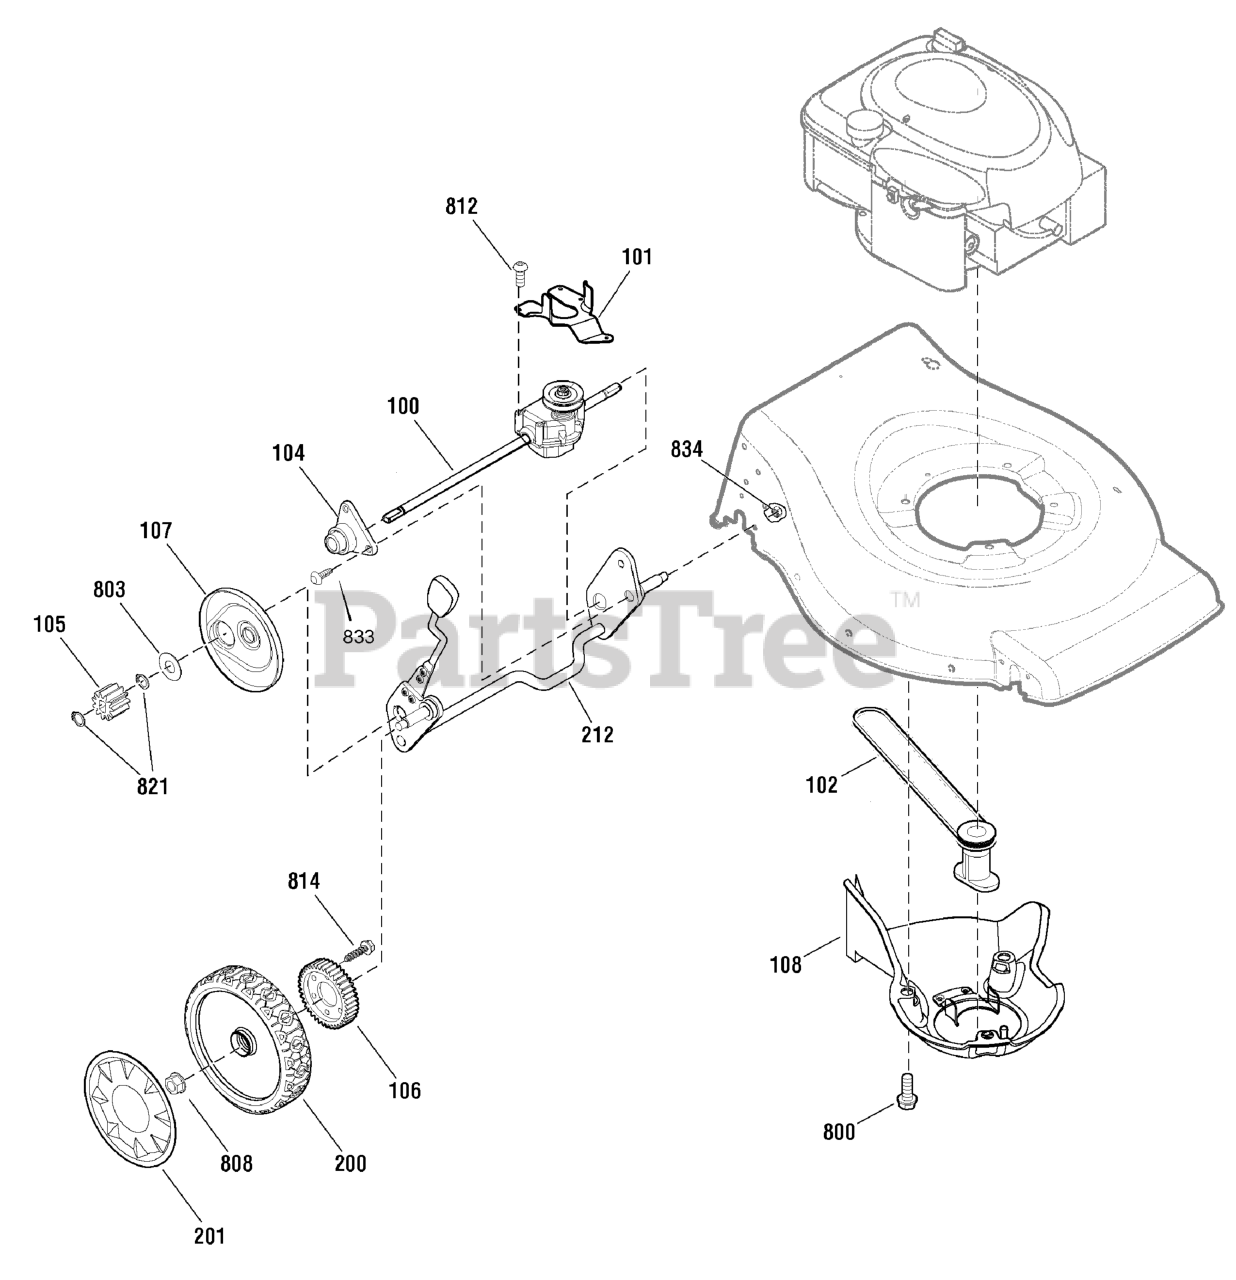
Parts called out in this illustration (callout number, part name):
100	TRANSMISSION
101	BELT GUIDE, Transmission
104	SLEEVE ASSEMBLY, Rear Axle
105	GEAR, Pinion
106	GEAR, Drive
107	DUST COVER
108	BELT COVER ASSEMBLY
200	WHEEL, Rear
201	HUBCAP, Rear
212	CROSSBAR, Rear
800	CAPSCREW, Hex Head, 3/8-16 x 1
803	WASHER, Thrust
808	NUT, Flange, 3/8-16
812	SCREW, #10 x 1
814	SCREW, 1/4-15 x 3/4
821	RING, External Retaining
822	NUT, Hex, 1/4-20
833	SCREW, Torx, 1/4-20 x 5/8
834	NUT, Flange Lock, 1/4-20
